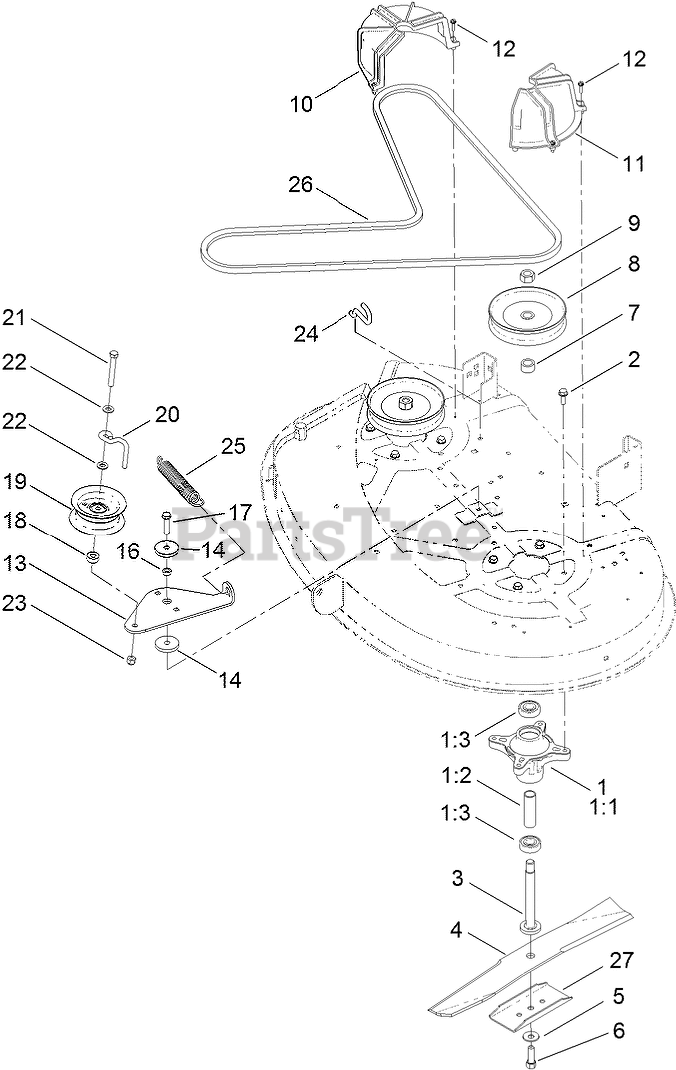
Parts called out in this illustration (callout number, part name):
1	SPINDLE ASM
1:1	SPINDLE
1:2	SPACER
1:3	BEARING-BALL
2	SCREW-TAPTITE
3	SHAFT-SPINDLE
4	BLADE-RECYCLING
5	WASHER-BELLEVILLE
6	SCREW-HH
7	SPACER-PULLEY
8	PULLEY
9	NUT-HEX
10	GUIDE-BELT, RH
11	GUIDE-BELT, LH
12	SCREW-SHWH, THREAD FORMING
13	ARM-IDLER
14	WASHER-PLAIN
16	SPACER
17	SCREW-HH
18	SPACER
19	PULLEY-IDLER, FLAT
20	GUIDE-IDLER, BELT
21	SCREW-HH
22	WASHER-FLAT
23	NUT-HF, NI
24	HOOK-RETURN, SPRING
25	SPRING-EXTENSION
26	BELT-V
27	STIFFENER-BLADE
